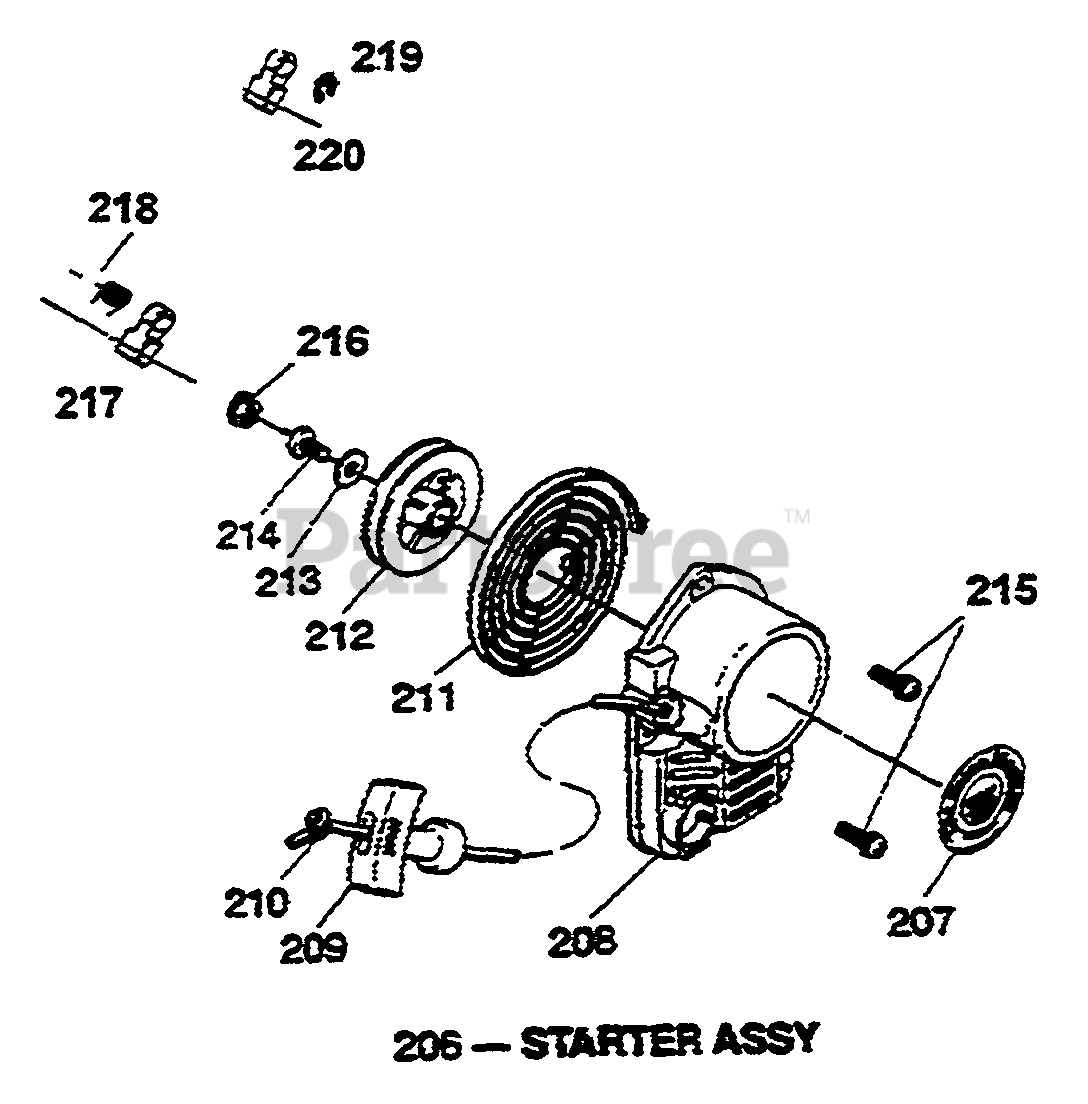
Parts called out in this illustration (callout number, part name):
206	STARTER ASSY (W/HOLE)
206	STARTER ASSY (WO/HOLE)
207	LABEL NAME
208	CASE, STARTER (W/HOLE)
208	CASE, STARTER (WO/HOLE)
209	KNOB, STARTER
210	ROPE, STARTER
211	SPRING, SPIRAL
215	BOLT AND WASHER
219	SNAP RING
